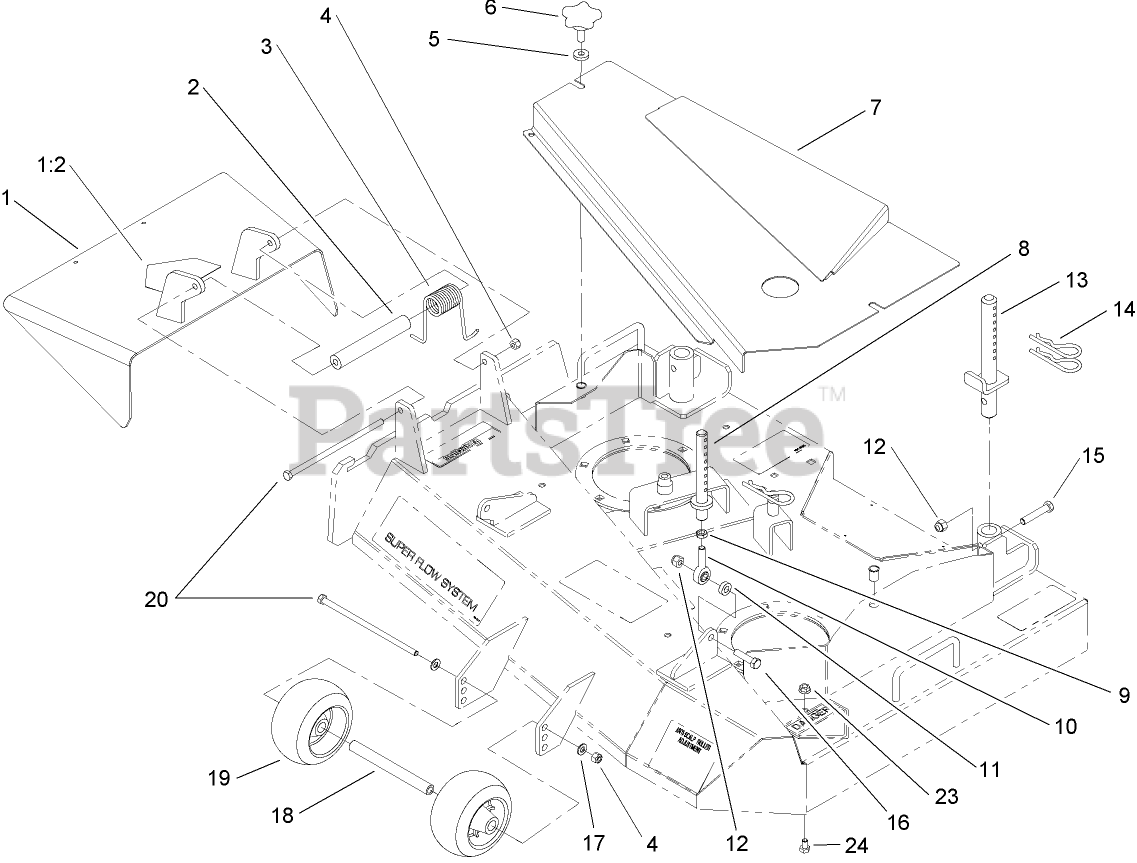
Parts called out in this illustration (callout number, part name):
1	Deflector ASM
1:2	DECAL-DANGER
2	SPACER
3	SPRING-TORSION
4	NUT-LOCK, NI
5	WASHER-RUBBER
7	Cover ASM
8	FRONT PIN ASM
9	NUT-HJ
10	BALLJOINT
11	SPACER
12	NUT-LOCK, NI
13	REAR PIN ASM
14	PIN-HAIR
15	SCREW-HH
16	SCREW-HH
17	WASHER-PLAIN
18	SPACER-WHEEL
19	WHEEL-GAGE
20	SCREW-HH
23	NUT-HF
24	SCREW-HH
